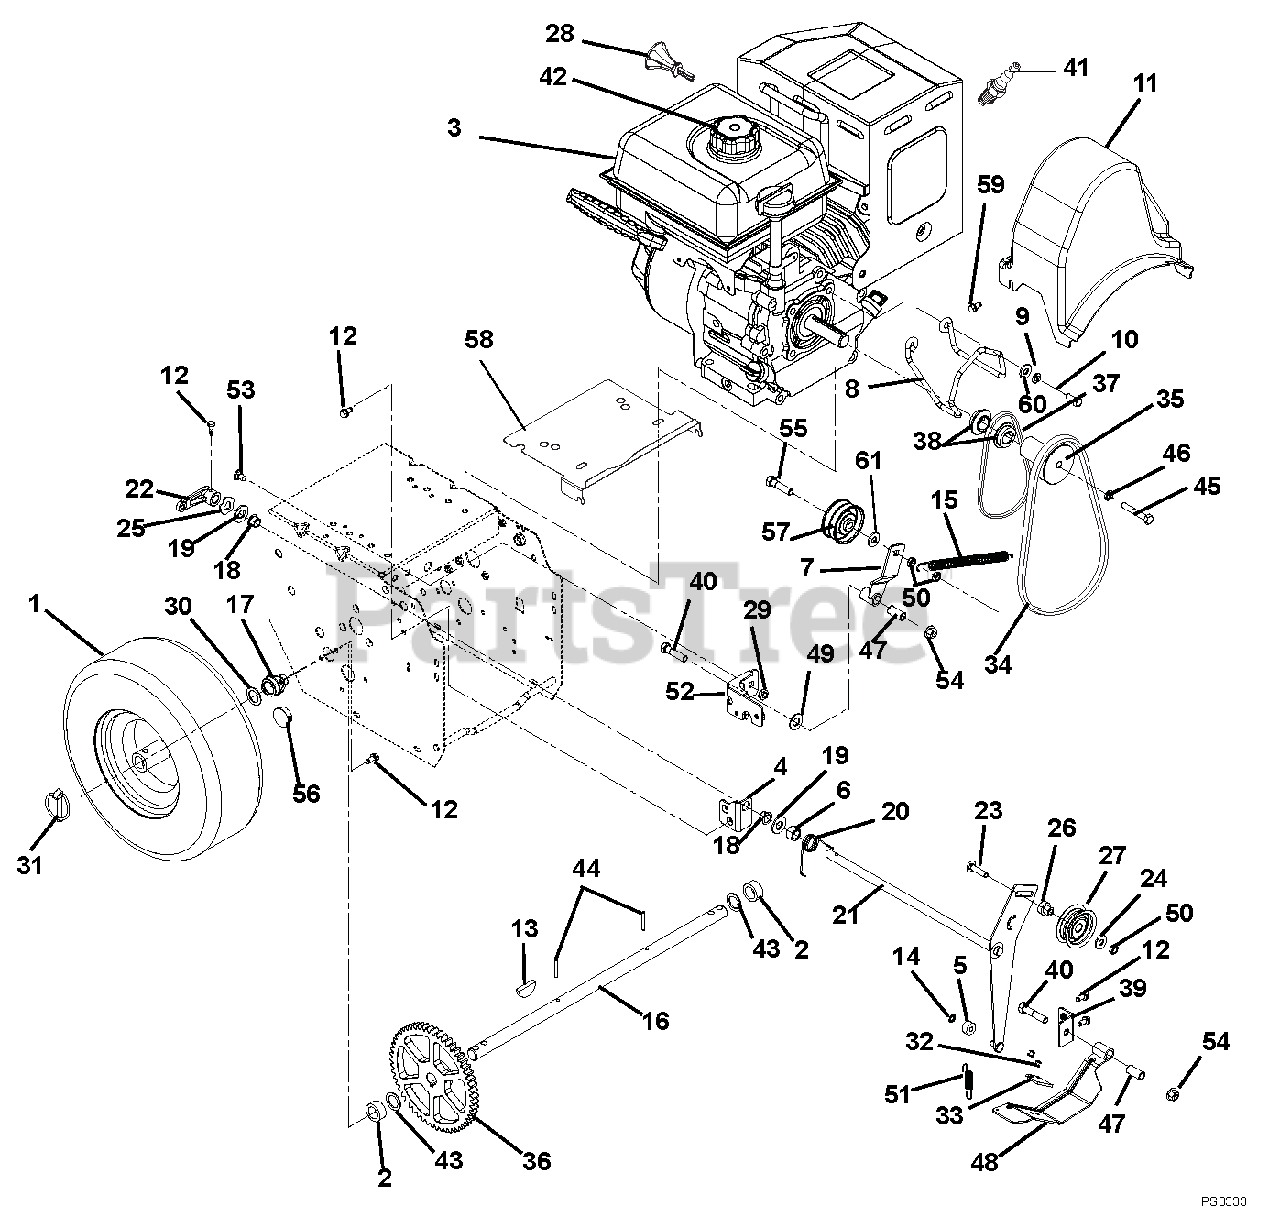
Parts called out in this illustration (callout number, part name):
1	TIRE/WHEEL, 13X4.10-6 K398A
1	TIRE/WHEEL, 15X5.00-6 K398A
1	TIRE, 13" K398A
1	TIRE, 15" K398A
2	BSHG-SLV .766 X 1.125 X .500
3	ENGINE,LCT STORMFORCE 208 RECL
3	ENGINE,LCT STORMFORCE 208 240V
3	ENGINE,LCT STORMFORCE 208 120V
4	BRACKET, MOUNT - IDLER ARM
5	BSHG,SLV .265 X .625 X .375
6	BSHG-SLV .510X.751X.475
7	WELDMENT, TRACTION IDLER ARM
8	FINGER, BELT
9	WSHR-LK .312X.097 HVY YWZC
10	BLT-HEX .31-24X.75 YWZC GR5
11	COVER, COMPACT BELT
12	SCR-TAP .25-20X.50 HWH TR YWZ
13	KEY-WDRF .25X.750X.313 SAE91
14	RG-RTNG-EXT .250X.010
15	SG-TENS .062X.56X8.0 WLD 11
16	SHAFT, AXLE
16	AXLE, COMPACT 920,XXX 15" TIRE
17	BSHG .75X1.125X.65
18	BUSHING, POLYLINER-.50 SPLIT
19	@WSHR-FL-STL.531X1.06X.095YWZC
20	SG-TORS .075 X .955
21	WELDMENT, ATTACHMENT IDLER ARM
22	ARM, CLUTCH - ATTACHMENT
23	BLT-RDHDSQSHNK.31-18X1.13 G5YZ
24	@WSHR-FL-STL.38X.875X.083 YWZC
25	WSHR-WAVE .50X.75X.015 .13FRHT
26	SPCR, BRG .315X.50X.688X.281
27	IDLER
28	KEY, PUSH/PULL LCT (2/PACKAGE)
29	@NUT-LK-TOP-FLG .31-18 YWZC
30	WSHR-FL-STL.754X1.125X.062YWZC
30	BSHG-SLV .75X1.12X1.062 NYL BK
31	PIN-LOK .31X1.75
32	RVT-POP .187 YZ
33	PAD, BRAKE
34	V-BELT, HA-RAW EDGE
35	SHEAVE, AUGER - COMPACT
36	SPUR GEAR, 54T .75ID X 6.75PD
37	V-BELT, 3L-WRAPPED
38	TRACTION SHEAVE HALF
39	BRACKET, MOUNT - BRAKE
40	@BLT-HEX .38-16X1.75 GR5 YWZC
41	PLUG, SPARK
42	CAP, FUEL TANK BLACK
43	WSHR-FL-STL.754X1.125X.062YWZC
44	PIN-ROLL .188X1.25
45	BLT-HEX .38-24X2.0 YWZC
46	@WSHR-LK .38X.094 REG YWZC
47	BSHG-SLV .385X.500X1.045
48	BRAKE ARM W/PAD
49	@WSHR-FL-STL.406X.812X.065 YWZ
50	@NUT-LK-CTR-JAM .31-18 YWZC
51	SPRING-EXT .437 X .438 X 2.64
52	WELDMENT, FRAME BRACKET
53	@BLT-RHDSSQNK .31-18X.62 G5YZ
54	@NUT-LK-TOP-FLG .38-16 YWZC
55	@BLT-HEX .31-18X1.75 GR5 YWZC
56	PLUG, HOLE - 1.00" FLEXTEMP
57	IDLER,1.875" OD
58	BAFFLE,ENGINE,SMALL BLOCK
59	SCR-TAP .25-20X.50 LGHWH TR YZ
60	@WSHR-FL-STL.344X.688X.065YWZC
61	WSHR-FL-STL .344X1.125X.135
